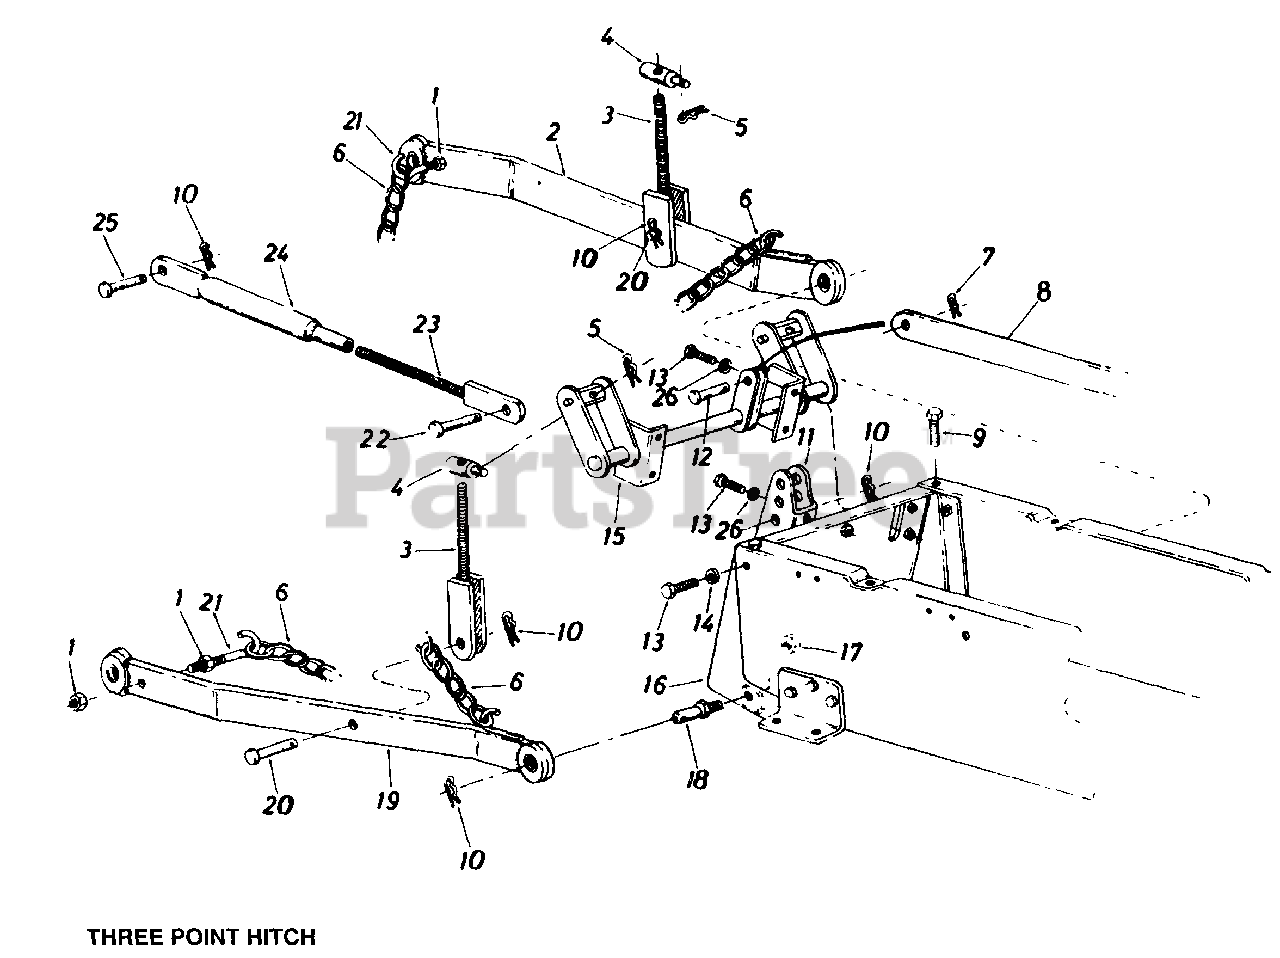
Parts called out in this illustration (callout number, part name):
1	Hex L-Nut 7/16-14 Thd.
4	Clevis Pin
5	Hitch Pin Clip
6	Chain - 20 Links
7	Cotter Pin 1/8" Dia. x 1.25" Lg.
10	Hairpin Cotter
12	Clevis Pin
13	Hex Bolt 3/8-16 x .75" Lg.
14	L-Wash. 3/8" I.D.- H.D.
18	Link Clevis Pin
21	Hitch Chain Hook
22	Clevis Pin .63" Dia. x 2.4" Lg.
23	Clevis Screw
25	Clevis Pin .63" Dia. x 2.4" Lg.
26	L-Wash. 3/8" I.D.- H.D.
